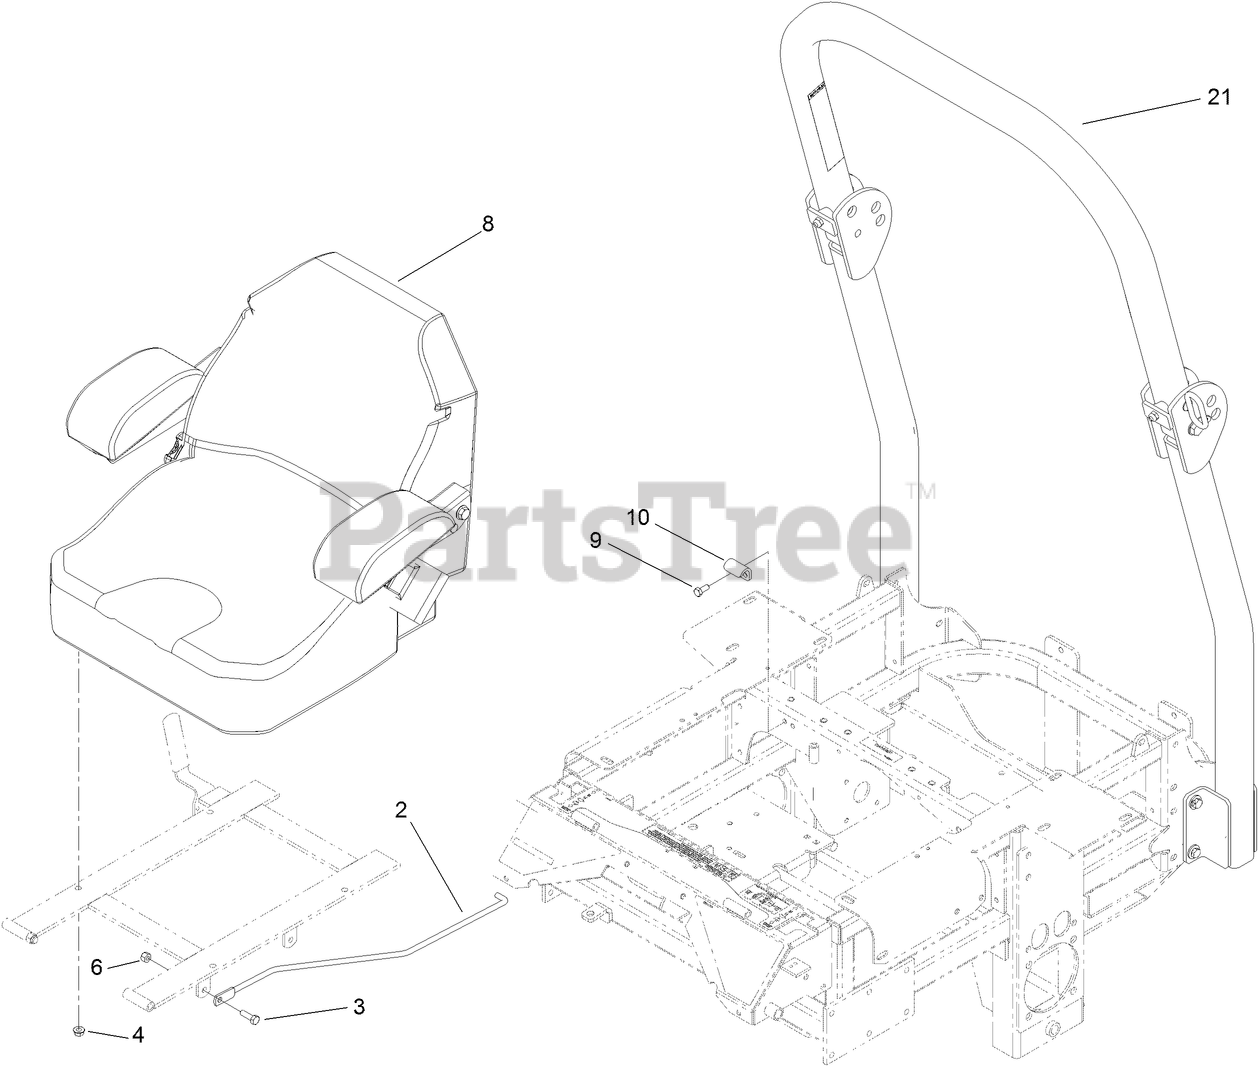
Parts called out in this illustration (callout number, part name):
2	ROD-PROP, SEAT
3	SCREW-HH
4	NUT-HF
6	NUT-LOCK, NI
8	SEAT-STANDARD
9	SCREW-HH
10	CATCH-LATCH, SEAT
21	ROPS KIT
